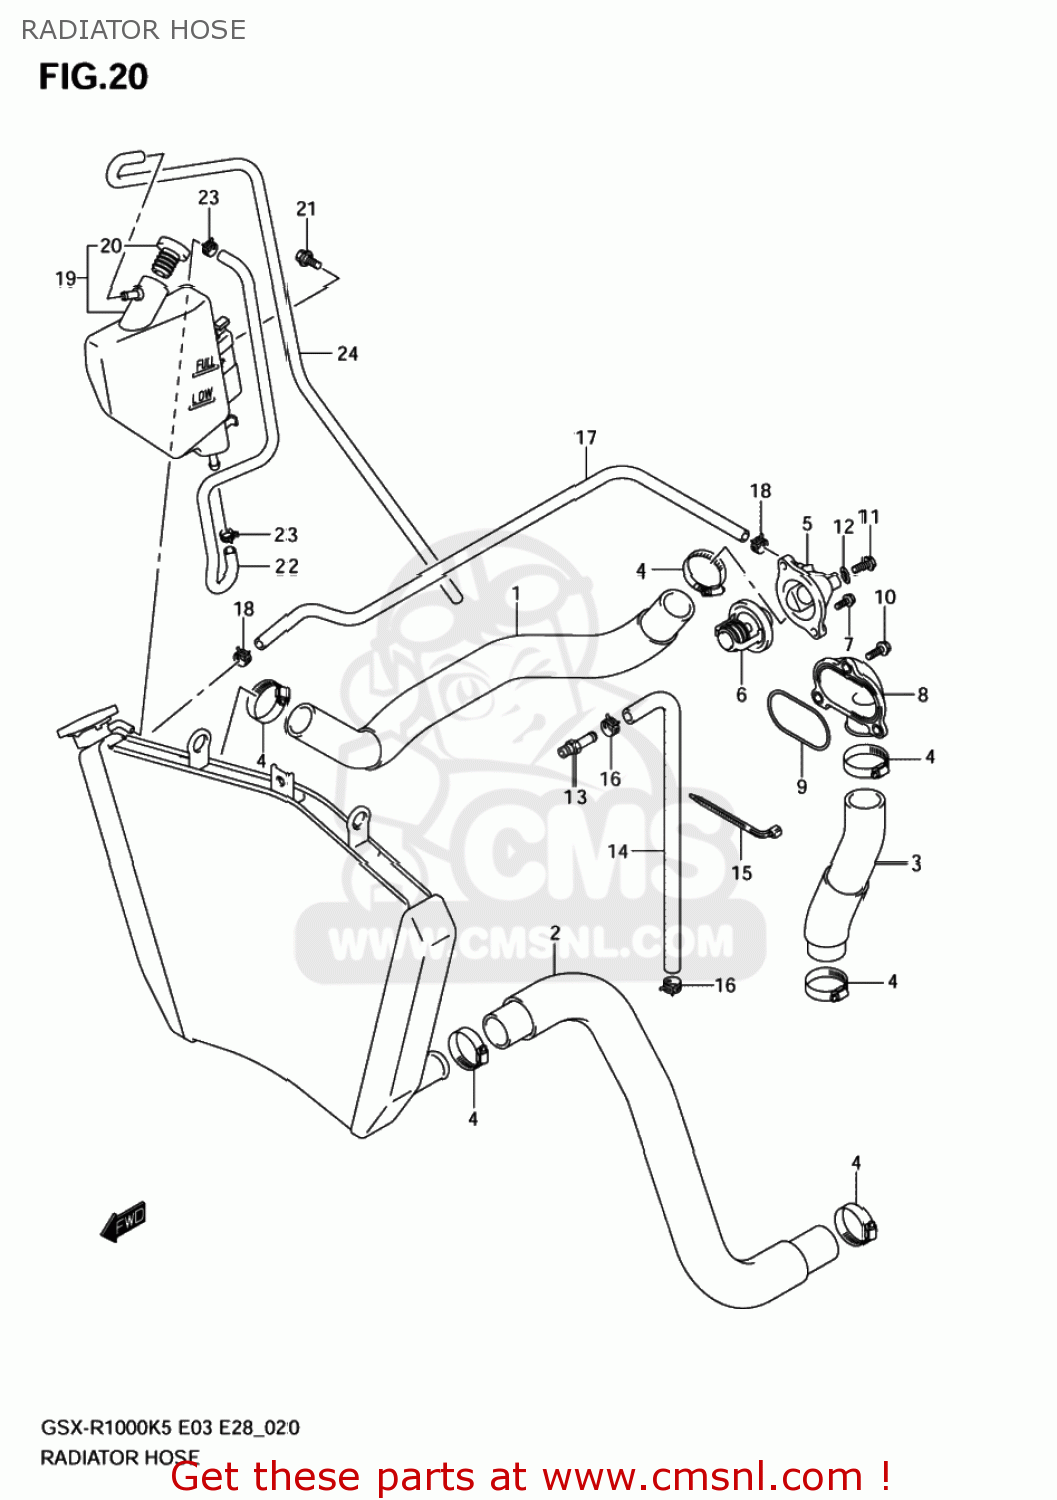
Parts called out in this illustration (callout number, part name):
1	HOSE,RADIATOR INLET
2	HOSE,RADIATOR OUTLET
3	HOSE,CYLINDER INLET
4	CLAMP
5	COVER,THERMOSTAT
6	THERMOSTAT,WATER
7	SCREW
8	CONNECTOR,CYL.
9	O RING,CYL WATER CONNECTOR
10	SCREW
11	UNION BOLT,AIR VENT
12	GASKET(6.4X11.5X0.8) (NAS)
13	BOLT UNION
14	HOSE,WATER BYPASS
15	CLAMP(L:165)
16	CLAMP
17	HOSE(5X11X600)
18	CLIP
19	TANK ASSY,RESERVOIR
20	CAP,RESERVOIR TANK
21	BOLT(6X12)
22	HOSE,RESERVOIR TANK INLET
23	CLIP
24	HOSE,RESERVOIR
